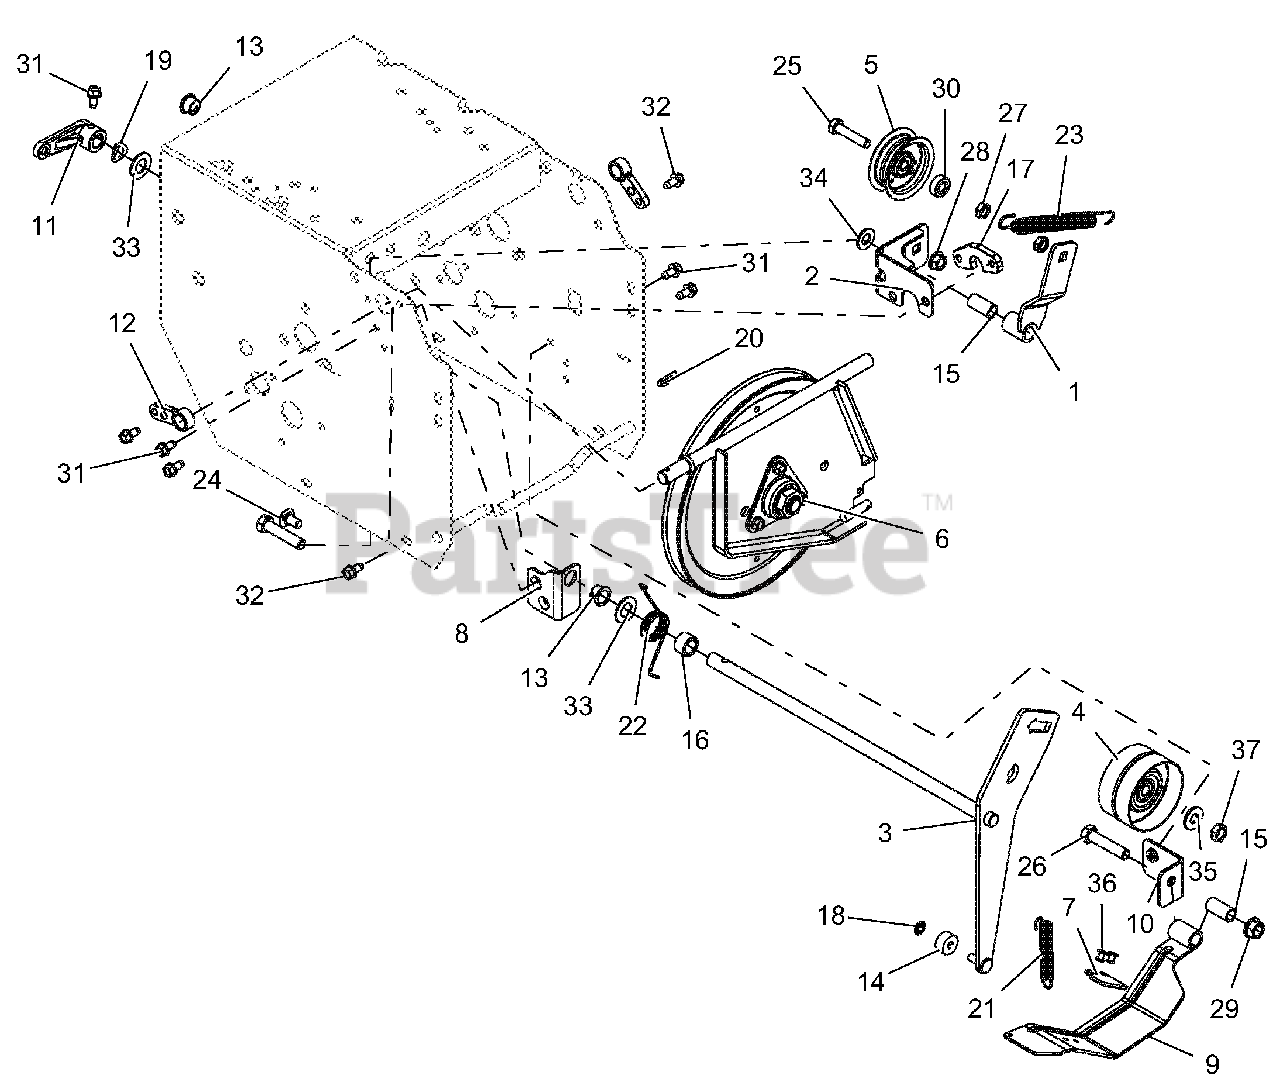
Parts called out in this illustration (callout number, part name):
1	ARM, TRACTION IDLER
2	WELDMENT, FRAME BRACKET
3	WELDMENT, ATTACHMENT IDLER ARM
4	IDLER, FLAT-2.75 OD X .375 ID
5	KIT, FLAT IDLER
6	PLATE, SWING - ASSEMBLY
7	PAD, BRAKE
8	BRACKET, MOUNT - IDLER ARM
9	BRAKE ARM W/PAD
10	BRACKET, BRAKE MOUNT
11	ARM, CLUTCH - ATTACHMENT
12	SUPPORT BUSHING, SWING GATE
13	BUSHING, POLYLINER-.50 SPLIT
14	BSHG,SLV .265 X .625 X .375
15	BSHG-SLV .385X.500X1.045
16	BSHG-SLV .510X.751X.475
17	SPACER, SWING GATE
18	RG-RTNG-EXT .250X.010
19	WSHR-WAVE .50X.75X.015 .13FRHT
20	CLIP, SPRING
21	SPRING-EXT .047 X .438 X 1.85
22	SG-TORS .075 X .955
23	SPRING, SWIVEL HOOK EXTENSION
24	@BLT-RHDSSQNK .31-18X.62 G5YZ
25	@BLT-HEX .31-18X1.50 GR5 YWZC
26	@BLT-HEX .38-16X1.75 GR5 YWZC
27	@NUT-LK-CTR-JAM .31-18 YWZC
28	@NUT-LK-TOP-FLG .31-18 YWZC
29	@NUT-LK-TOP-FLG .38-16 YWZC
30	SPCR, BRG .315X.500X.358X.281
31	SCR-TAP .25-20X.50 HWH TR YWZ
32	SCR-TAP .25-20X.50 HWH TR YWZ
33	WSHR-FL-STL.531X1.00X.063 YWZC
34	@WSHR-FL-STL.406X.812X.065 YWZ
35	@WSHR-FL-STL.38X.875X.083 YWZC
36	RVT-POP .187 YZ
37	@NUT-LK-CTR-JAM .375-16 YWZC
